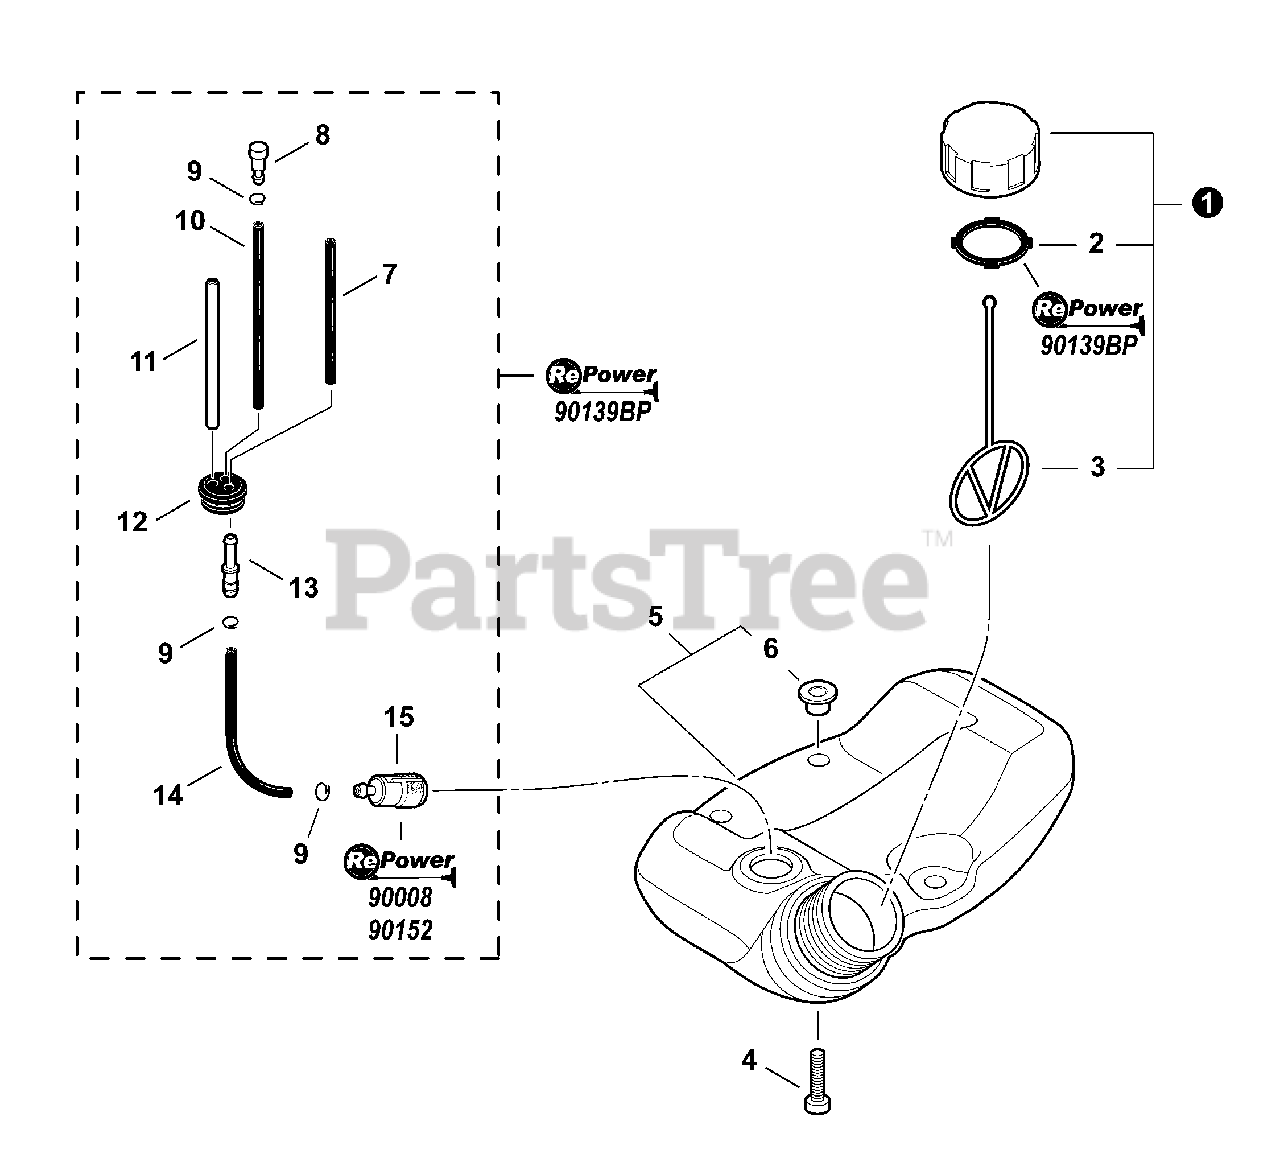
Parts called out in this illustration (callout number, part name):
1	CAP ASSY
2	GASKET, CAP
3	CONNECTOR, CAP
4	SCREW - 5×20
5	FUEL TANK ASSY
7	PIPE - 3×5×74 -- BLACK
8	VENT, FUEL TANK
9	CLIP - 6
10	PIPE - 3×5×90 -- BLACK
11	PIPE - 3×6×80 -- CLEAR
13	CONNECTOR, FUEL PIPE
14	PIPE, FUEL
15	FILTER, FUEL
